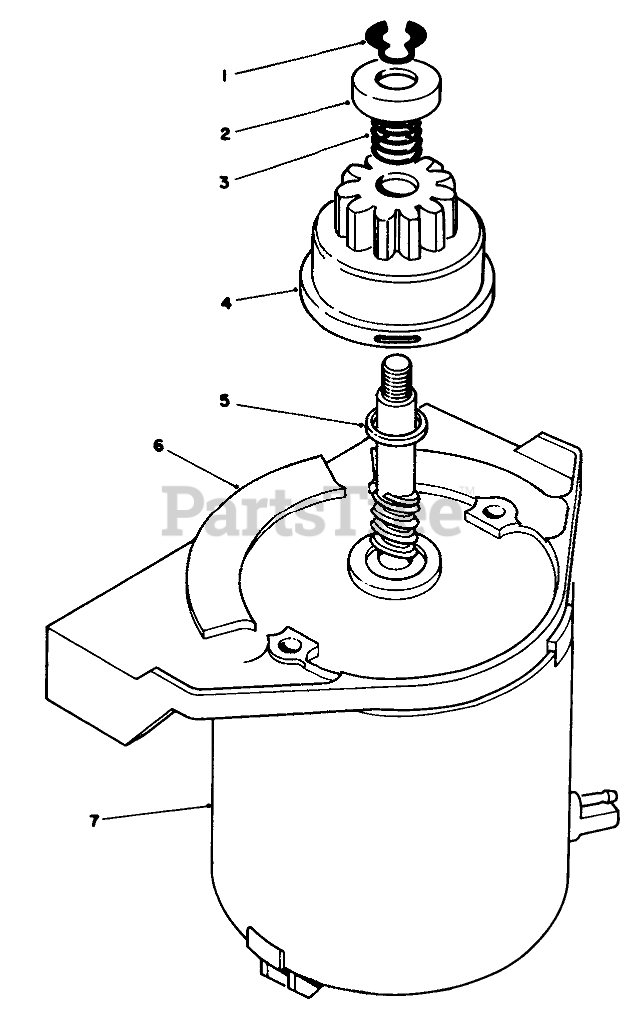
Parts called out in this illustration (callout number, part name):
1	RING-RETAINING
2	PINION STOP
3	COMPRESSION SPRING
4	PINION ASM
5	SPACER
6	Motor-Starter (Incl. Ref. #7)
7	END FRAME ASSY, MOTOR
